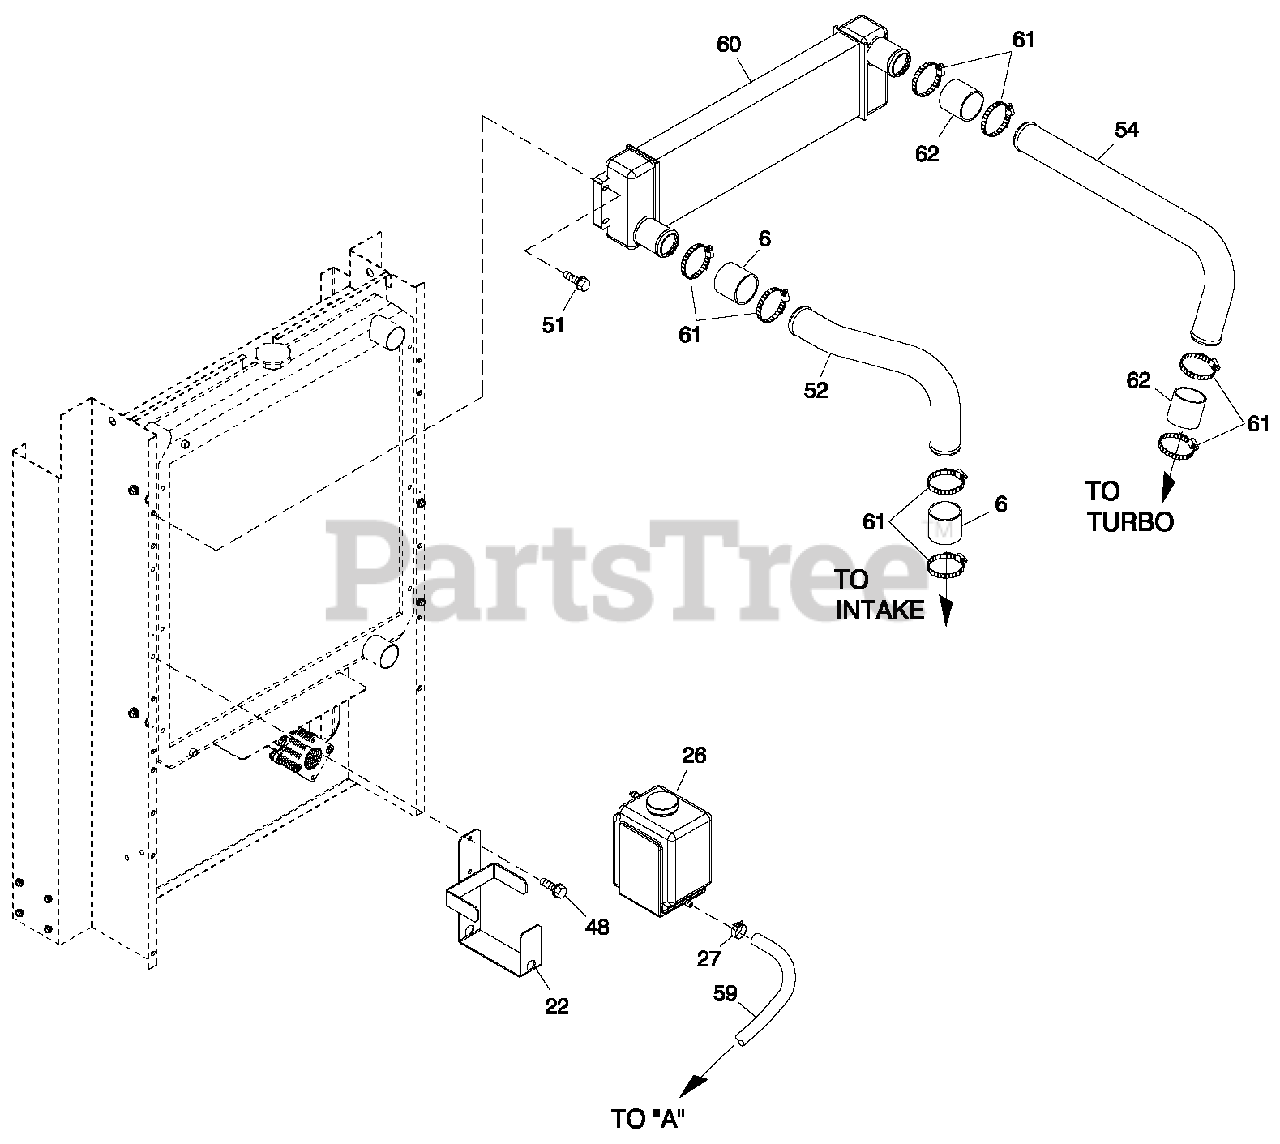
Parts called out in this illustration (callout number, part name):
6	HOSE 2"IDX 3.0 "LG
22	BRACKET COOLANT TANK
26	TANK COOLANT RECOVERY
27	CLAMP HOSE BAND 1/4
28	BEARING #6205 2NSE C3 E SRI2 S
48	SCREW THF M6-1 X 16 N WA Z/JS
51	SCREW THF M6-1 X 30 N WA DELTA
52	TUBE CAC OUT G2 TURBO
54	TUBE CAC IN
59	HOSE 9/32 ID (36" LG)
60	CAC 504W X 152H X 50D 2.4L G2
61	CLAMP CNST TENSION 1.75-2.625
62	HOSE 2 "ID X 3.0"LG
